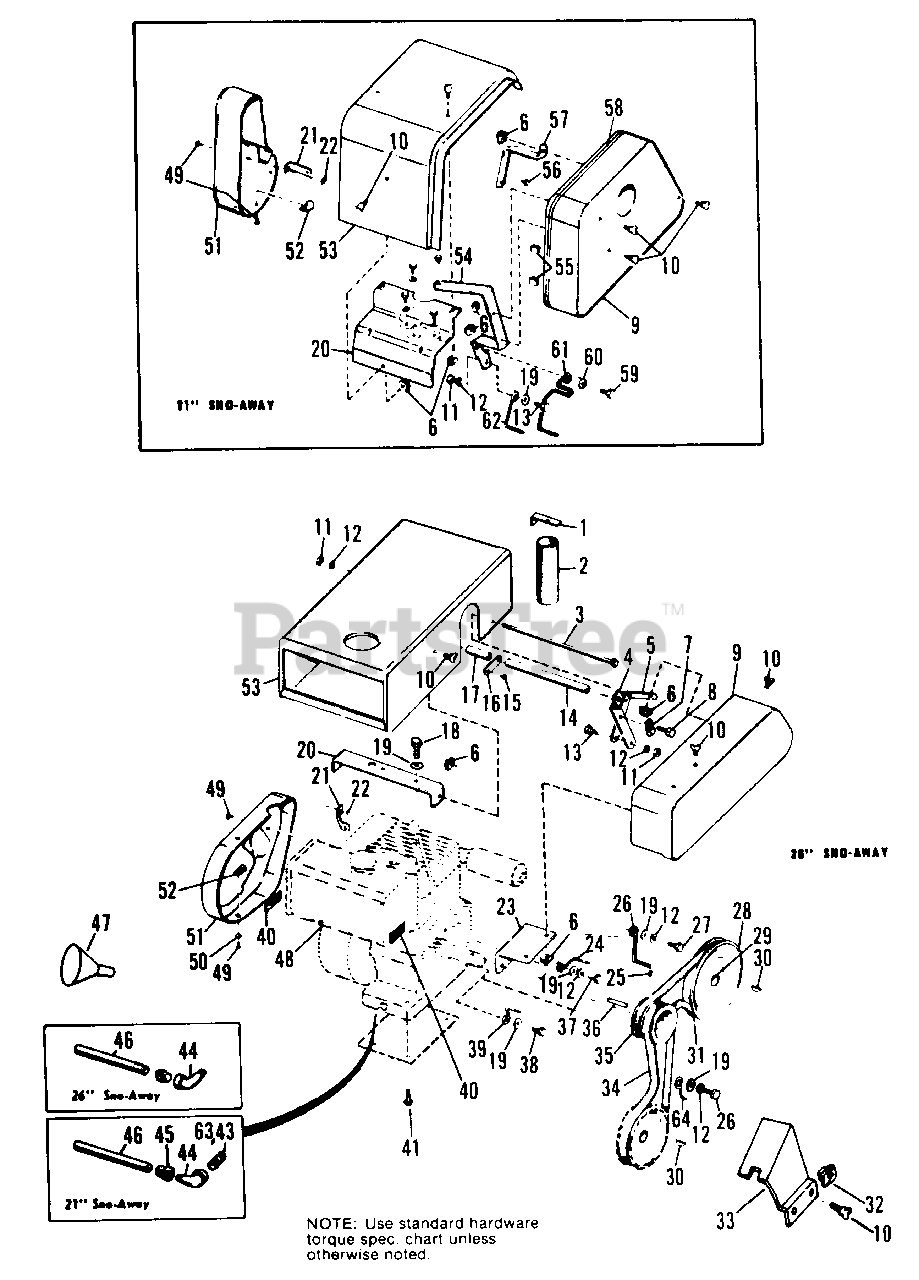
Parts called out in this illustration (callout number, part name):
1	CLAMP, Tube (990483 & 990559 Only)
2	TUBE, Rubber (990483 & 990559 Only)
3	BOLT, Hood Spacer (990483 & 990559 Only)
4	SUPPORT, Hood, Rear (990483 & 990559 Only)
5	BRACE, Belt Guard (990483 & 990559 Only)
6	NUT, Retainer, 5/16-18
7	CLAMP (990483 8 990559 Only)
8	SCREW, Hex Washer Hd., Taptite, 1/4-20 x 3/8 (990483 & 990559 Only)
9	GUARD ASSY., Belt (990483 & 990559 Only)
9	GUARD ASSY., Belt (990482 & 990558 Only)
10	SCREW, Thumb 5/16-18 x 3/4
11	NUT, Hex, Full, 5/16-18 (Qty. 1 used on 990482 & 990558 Only)
12	LOCKWASHER, 5/16 (Qty. 1 used on 990482 & 990558 Only)
13	CAPSCREW, Hex Hd., 5/16-18 x 1
14	SPACER, Hood L.H. (990483 & 990559 Only)
15	SCREW, Rd. Hd., #10-32 x 3/8 (990483 & 990559 Only)
16	BRACE (990483 & 990559 Only)
17	SPACER, Hood, R.H. (990483 & 990559 Only)
18	CAPSCREW, Hex Hd., 5/16-18 x 5/8
19	WASHER, Plain 5/16 (Qty. 1 used on 990482 & 990558 Only)
20	SUPPORT, Hood (990483 & 990559 Only)
20	SUPPORT, Hood (990482 & 990558 Only)
21	BRACKET, Cover (990483 & 990559 Only)
21	BRACKET, Cover (990482 & 990558 Only)
22	NUT, Speed
23	SUPPORT, Guard (990483 & 990559 Only)
24	STOP, Belt (990483 & 990559 Only)
25	SETSCREW, 5/16-18 x 3/8
26	STOP, Belt (990483 & 990559 Only)
27	CAPSCREW, Hex Hd., 5/16-24 x 3/4 (990483 & 990559 Only)
28	PULLEY, Transmission Drive
29	SETSCREW, 5/16-18 x 5/16
30	KEY, Woodruff
32	NUT, Retainer 5/16-18
33	COVER, Belt (990483 & 990559 Only)
33	COVER, Belt (990482 & 990558 Only)
35	PULLEY, Engine (990483 & 990559 Only)
35	PULLEY, Engine (990482 & 990558 Only)
36	KEY (990483 & 990559 Only)
36	KEY (990482 & 990558 Only)
37	CAPSCREW, Hex Hd., 5/16-18 x 3/4 (990483 & 990559 Only)
38	CAPSCREW, Hex Hd., 5/16-24 x 5/8 (990483 & 990559 Only)
39	STOP, Belt (990483 & 990559 Only)
40	PAD, Belt (990483 & 990559 Only)
41	SCREW, Hex, Washer Hd., Taptite, 3/8-16 x 1-1/4
43	SCREW, Hex, Washer Hd., Taptite, 3/8-16 x 1
44	(990482 & 990558 Only)
44	NIPPLE, Pipe (990482 & 990558 Only)
45	ELBOW, Street, 90ø (990483 & 990559 Only)
46	ELBOW, Street (990482 & 990558 Only)
47	CAP, Pipe (990482 & 990558 Only)
48	ENGINE, 6 HP, Briggs & Stratton, Model 100202, Type 0180-01 (990483 & 990559 Only) ENGINE, 4 H.P. (990482 & 990558 Only)
49	SCREW, Self Tapping #10 x 1/2
50	WASHER, Plain, 3/16 (990483 & 990559 Only)
51	COVER, Air Cooling (990483 & 990559 Only)
51	COVER, Air Cooling (990482 & 990558 Only)
52	NUT, Retainer
53	HOOD, ASSY. (990483 & 990559 Only)
53	HOOD, ASSY. (990482 & 990558 Only)
54	SUPPORT, Belt Guard (990482 & 990558 Only)
55	CLIP, Speed (990482 & 990558 Only)
56	SCREW, Hex Hd., Self Tapping, 1/4-20 x 3/8 (990482 & 990558 Only)
57	BRACKET, Belt Guard (990482 & 990558 Only)
58	STRIPE, White (990482 & 990558 Only)
59	CAPSCREW, Hex Hd., 1/2-20 x 1 (990482 & 990558 Only)
60	LOCKWASHER, Int., 1/2 (990482 & 990558 Only)
61	STOP, Belt (990482 & 990558 Only)
62	STOP, Belt (990482 & 990558 Only)
63	NIPPLE, Pipe (990482 Only)
64	STOP, Belt (990483 Only)
